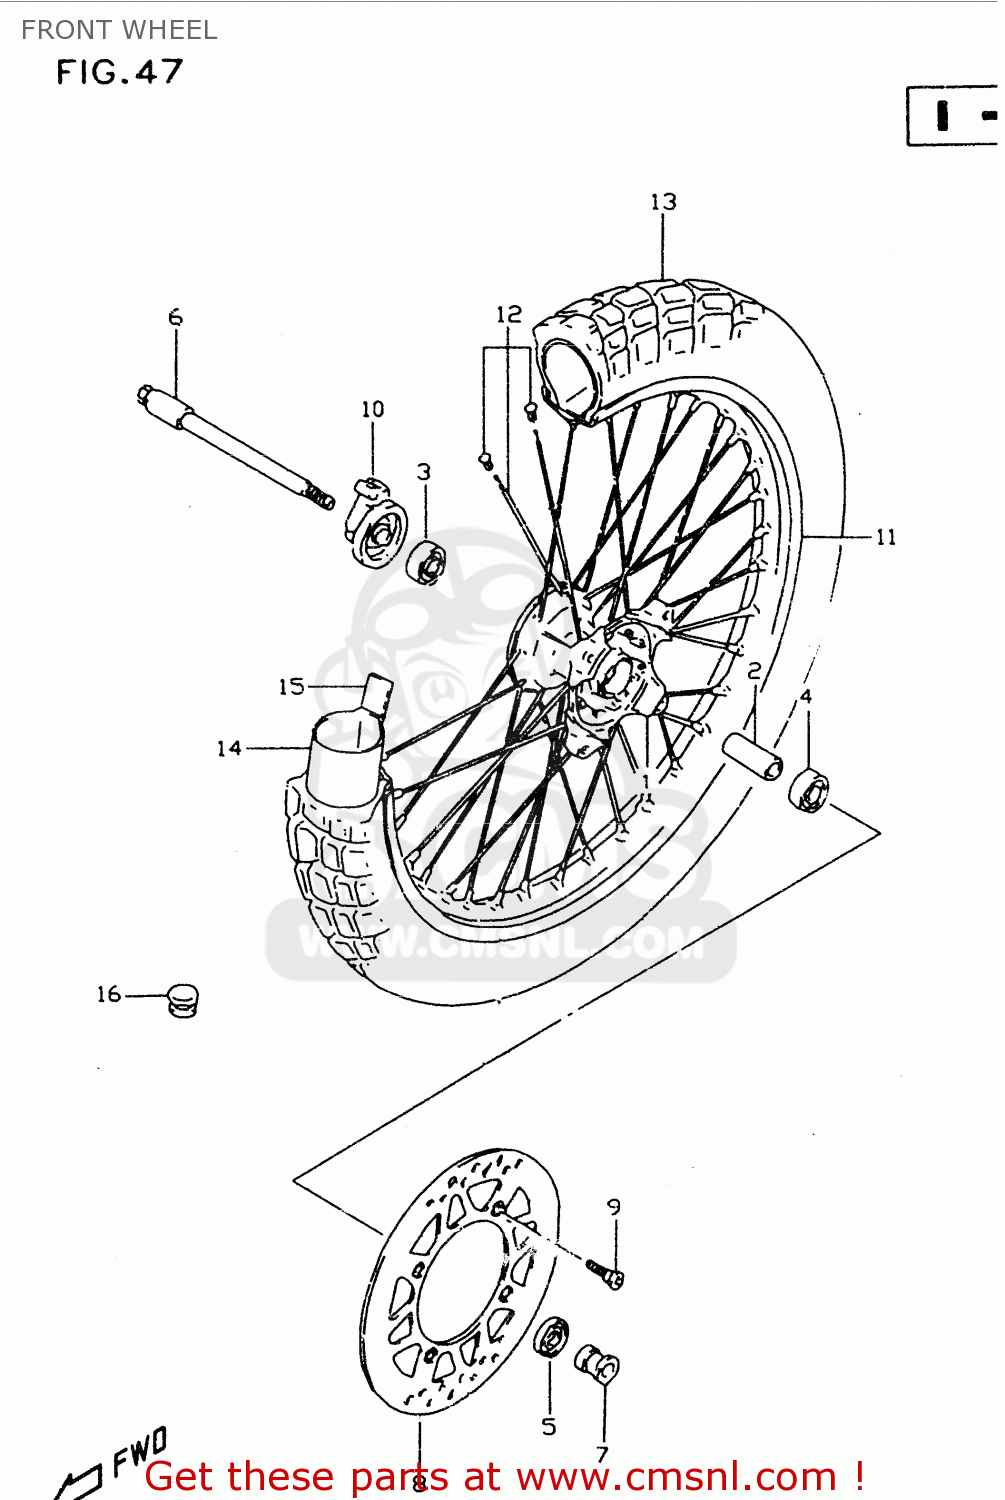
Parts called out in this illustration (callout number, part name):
1	HUB,FR WHEEL
2	SPACER,FR HUB BEARING
3	BEARING
4	BEARING
5	SEAL,OIL(22X35X5)
6	AXLE,FR
7	SPACER,FR AXLE,L
8	DISC,FR BRAKE
9	BOLT,BRAKE DISC
10	BOX ASSY,SPEEDOMETER GEAR
11	RIM,FR WHEEL(1.60X21)
12	SPOKE SET,FR WHEEL
13	TIRE,FR(80/100-21)
14	TUBE
15	PROTECTOR,WHEEL INNER
16	CAP, BEAD STOPPER
